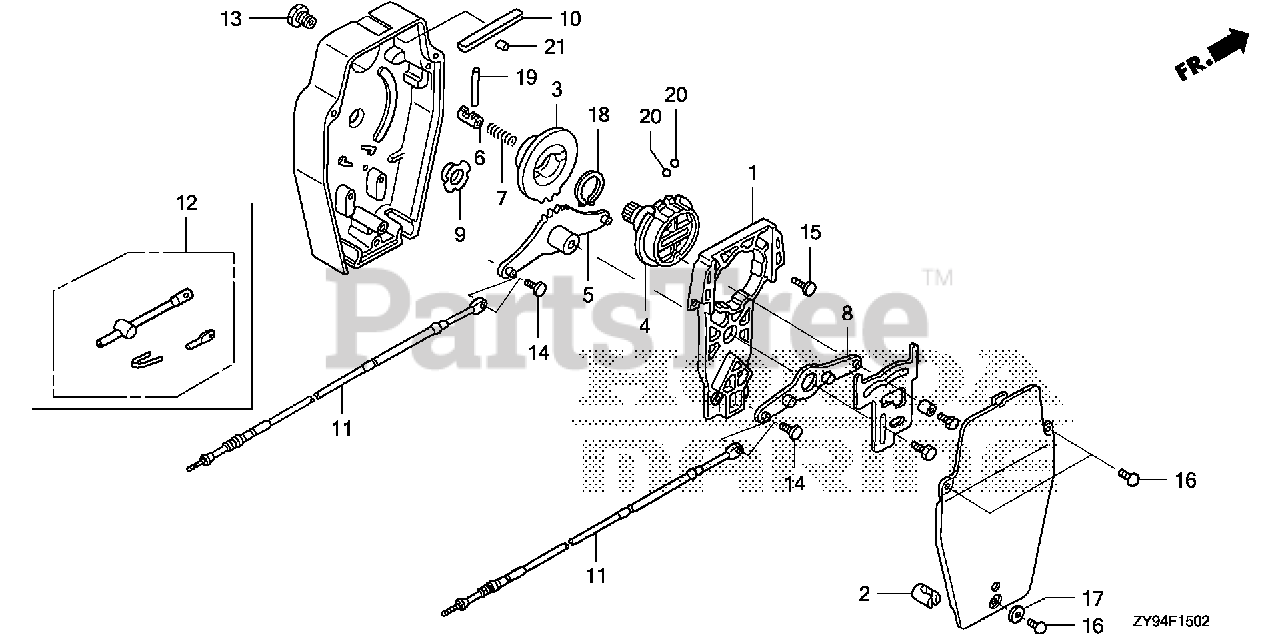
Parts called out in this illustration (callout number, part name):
1	FRAME ASSY., REMOTE CONTROL BOX
2	GROMMET
3	WHEEL, CONTROL
4	SHAFT, HANDLE (NOT AVAILABLE)
5	ARM ASSY., SHIFT LINK
6	SHAFT, GEARSHIFT
7	SPRING, GEARSHIFT
8	ARM ASSY., THROTTLE LINK
9	BUSH
10	SPRING
11	CABLE, REMOTE CONTROL (10') (TELEFLEX)
11	CABLE, REMOTE CONTROL (10') (BRUNSWICK)
11	CABLE, REMOTE CONTROL (11') (TELEFLEX)
11	CABLE, REMOTE CONTROL (11') (BRUNSWICK) (NOT AVAILABLE)
11	CABLE, REMOTE CONTROL (12') (TELEFLEX)
11	CABLE, REMOTE CONTROL (12') (BRUNSWICK) (NOT AVAILABLE)
11	CABLE, REMOTE CONTROL (13') (TELEFLEX)
11	CABLE, REMOTE CONTROL (13') (BRUNSWICK) (NOT AVAILABLE)
11	CABLE, REMOTE CONTROL (14') (TELEFLEX)
11	CABLE, REMOTE CONTROL (14') (BRUNSWICK) (NOT AVAILABLE)
11	CABLE, REMOTE CONTROL (15') (TELEFLEX)
11	CABLE, REMOTE CONTROL (15') (BRUNSWICK) (NOT AVAILABLE)
11	CABLE, REMOTE CONTROL (16') (TELEFLEX)
11	CABLE, REMOTE CONTROL (16') (BRUNSWICK) (NOT AVAILABLE)
11	CABLE, REMOTE CONTROL (17') (TELEFLEX)
11	CABLE, REMOTE CONTROL (17') (BRUNSWICK) (NOT AVAILABLE)
11	CABLE, REMOTE CONTROL (18') (TELEFLEX)
11	CABLE, REMOTE CONTROL (18') (BRUNSWICK) (NOT AVAILABLE)
11	CABLE, REMOTE CONTROL (19') (TELEFLEX)
11	CABLE, REMOTE CONTROL (19') (BRUNSWICK) (NOT AVAILABLE)
11	CABLE, REMOTE CONTROL (20') (TELEFLEX)
11	CABLE, REMOTE CONTROL (20') (BRUNSWICK) (NOT AVAILABLE) (ALT. PNO: 24920-ZW1-003AH)
12	ADAPTER, REMOCON CABLE (N/A: USE 24931-ZW1-000)
13	BOLT
14	SCREW (8-32X3/8)
15	SCREW (10-32X5/8)
16	SCREW (10-32X5/8)
17	WASHER
18	CIRCLIP (OUTER)
19	PIN, GEARSHIFT
20	BALL, STEEL
21	ROLLER, SHIFT CLICK
